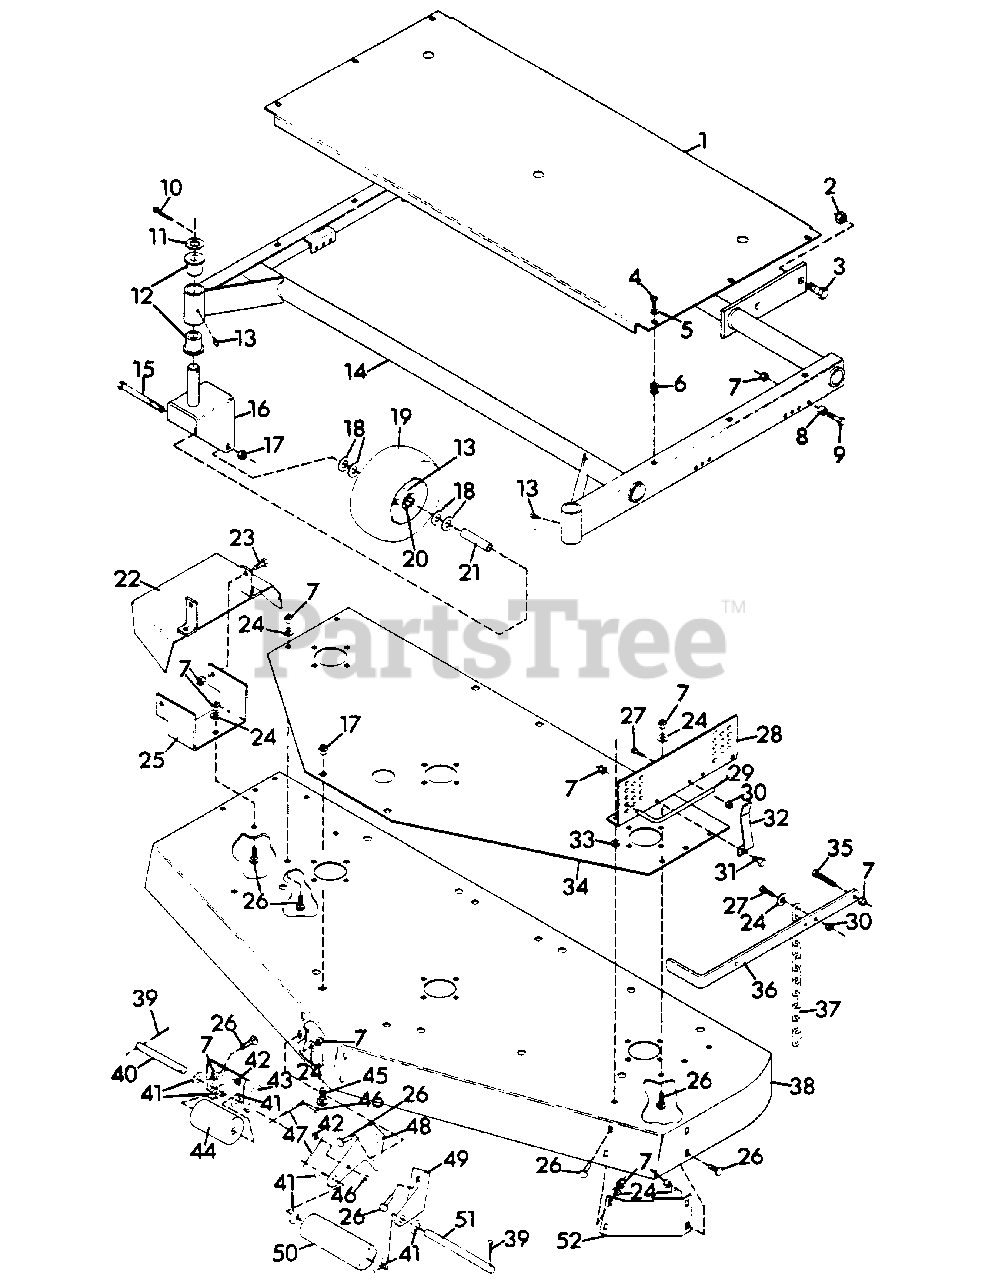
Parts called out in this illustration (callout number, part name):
1	GUARD, BELT PRO-60
2	NUT, LOCK 5/8-11
3	BOLT, HEX 5/8-11X1.50
4	SCREW, MACH. 1/4-20X.625 RD HD
5	WASHER, FLAT .281X.625X.065
6	GROMMET, PLASTIC
7	NUT, LOCK 3/8-16
8	BUSHING .391X.622X.670
9	BOLT, HEX 3/8-16X1.50
10	PIN, COTTER .187X1.62
11	RACE, BEARING THRUST
12	BUSHING, PIVOT
13	FITTING, LUBE 1/4-28
14	WELDMENT, MOWER FRAME
15	BOLT, HEX 1/2-13X5.00
16	WELDMENT, CASTER FORK
17	NUT, LOCK 1/2-13
18	WASHER, FLAT .531X1.25X.100
19	WHEEL, GAUGE
20	BEARING, GAUGE WHEEL
21	BUSHING, WHEEL .520X.750X3.312
22	WELDMENT, DISCHARGE CHUTE
23	BOLT, HEX 3/8-16X1.00
24	WASHER, FLAT .406X.812X.065
25	BRACKET, DISCHARGE CHUTE
26	BOLT, 3/8-16X1.00 RD HD SQ NK
27	BOLT, HEX 5/16-18X1.00
28	BRACKET, MOWER SUPPORT L.H.
28	BRACKET, MOWER SUPPORT R.H.
29	PIN, MOWER LOCKING
30	NUT, LOCK 5/16-18
31	BOLT, HEX 3/8-16X.75
32	SPRING, PIN
33	SPACER, IDLER .406X.750X.188
34	PLATE, SUPPORT
35	BOLT, HEX 3/8-16X2.00
36	BAR, LIFT
37	CHAIN, HEIGHT ADJUSTMENT
38	WELDMENT, 60" MOWER
39	PIN, COTTER .25X1.0
40	ROD
41	WASHER, FLAT .656X1.312X.095
42	NUT, HEX 1/4-20
43	BRACKET, ROLLER
44	ROLLER, GAGE
45	BOLT, 1/2-13X1.00 RD HD SQ NK
46	BOLT, HEX 1/4-20X.75
47	PIN, COTTER .25X2.0
48	BRACKET, ROLLER R.H.
49	BRACKET, ROLLER L.H.
50	ROLLER, GAUGE
51	SHAFT, CENTER ROLLER
52	BAFFLE, FRONT
NS	DECAL, DANGER HAND
NS	DECAL, DANGER FOOT
NS	DECAL, WARNING EYE
NS	STRIPE
NS	DECAL, LUBE
NS	DECAL, GRAVELY LOGO
NS	DECAL, PRO-60
